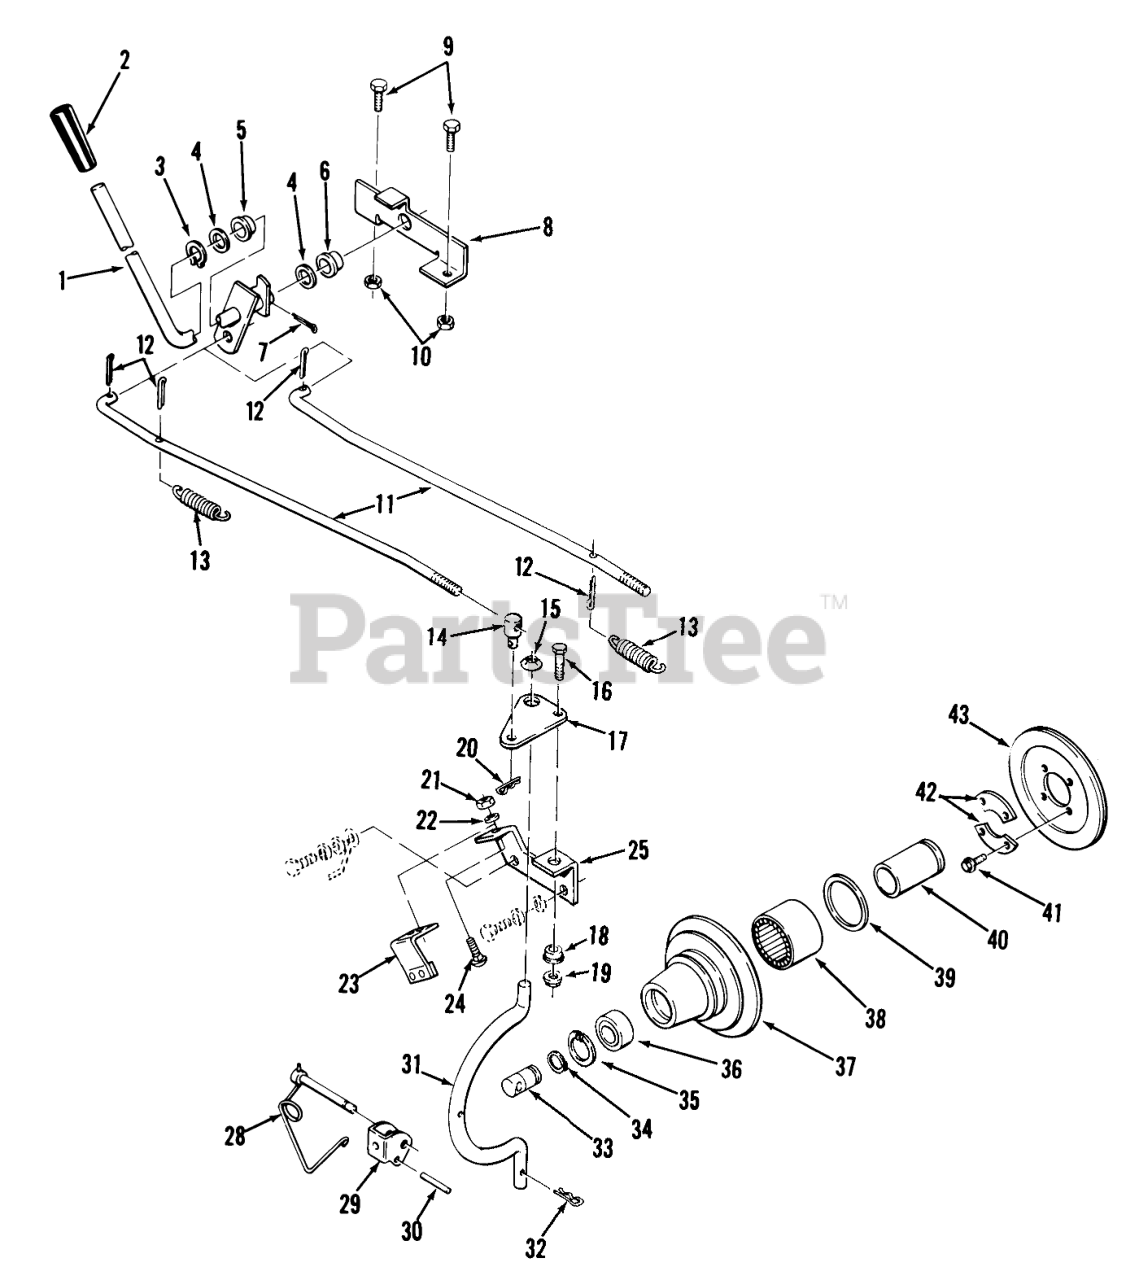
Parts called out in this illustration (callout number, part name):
1	PTO Clutch Lever
2	GRIP
3	Grip Ring
4	SHIM-WASHER
5	BUSHING-NYLINER
6	NYLINER BUSHING
7	Pop Rivet
8	SUPPORT-PTO CLUTCH
9	Bolt
10	Nut
11	PTO Clutch Rod
11	PT0 Clutch Rod
12	Pop Rivet
13	SPRING
14	TRUNNION
15	RING-REINFORCED CIRC
16	BOLT
17	PTO Plate
18	SPACER-LIFT LINK
19	LOCKNUT-FLANGE
20	Hairpin Cotter
21	Nut
23	PTO Plate
24	Bolt-Carriage
25	BRACKET
25	BRACKET-ENGINE B
28	Pin
29	Clevis
30	PIN-SPIROL
31	ROD-HOUSING
31	PTO Housing Rod C-175 Twin Only
32	Hairpin
33	SHAFT-PTO
34	RING-SNAP, EXTERNAL
35	Ring-Snap
36	BaIl Bearing
37	Housing-Clutch
38	BRG-NEEDLE OPEN END
39	SEAL-OIL
40	RACE-BEARING
40	BEARING RACE
41	Screw
42	RETAINER
43	Clutch Plate & Facing
